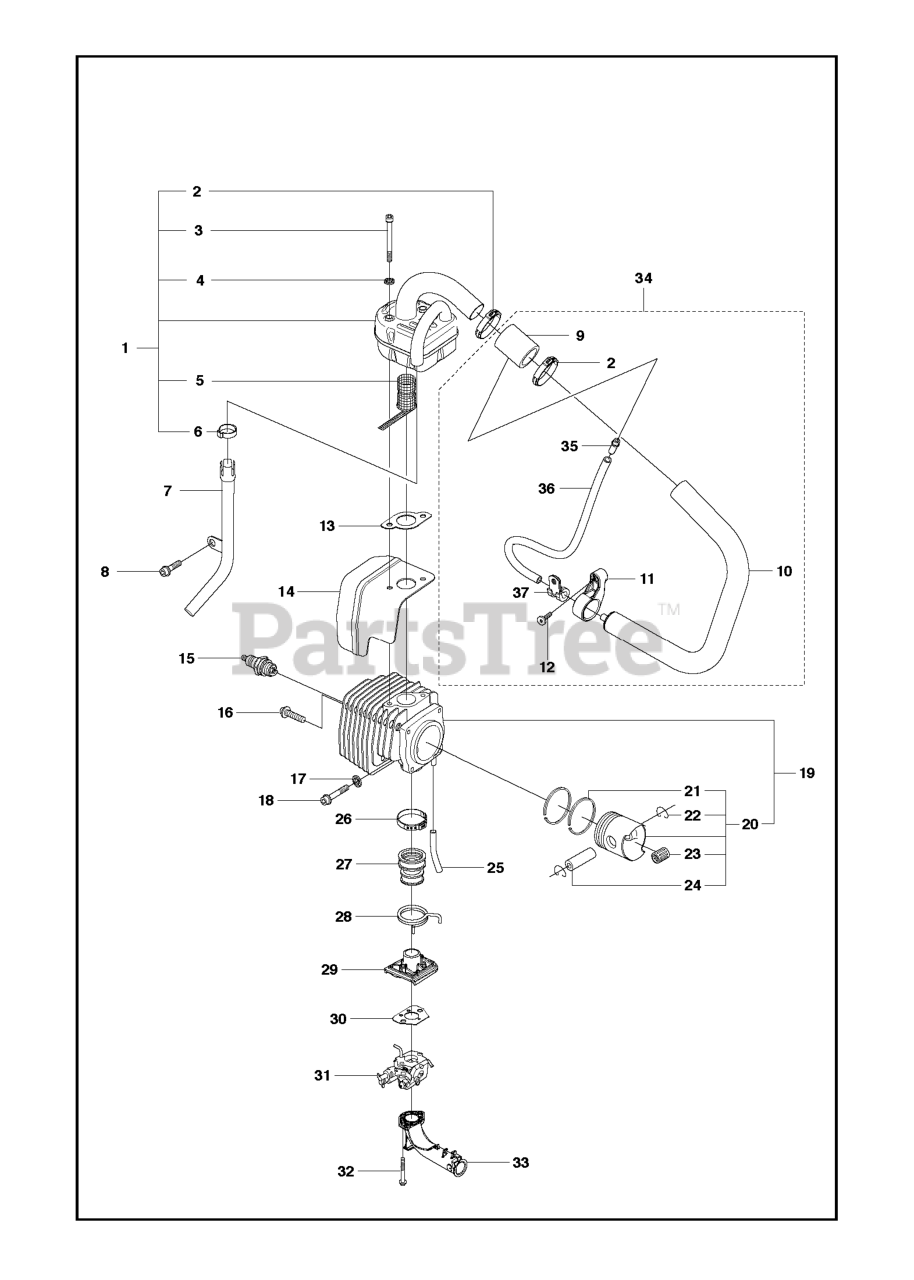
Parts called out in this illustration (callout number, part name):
4	DOUBLE WASHER
5	SPARK ARRESTOR
9	HOSE
10	PIPE COMPLETE BLAIR TUBE
12	SCREW M5X14
15	SPARK PLUG RCJ7Y
16	SCREW MC6S 5X25
17	DOUBLE WASHER
20	PISTON CPL 44MM
21	PISTON RING
22	WRIST PIN CLIP
23	BEARING
24	PISTON BOLT
27	INLET TUBE
31	CARBURETOR
33	INLET BEND 5MM WIRE
34	PIPE COMPLETE BLAIR TUBE
